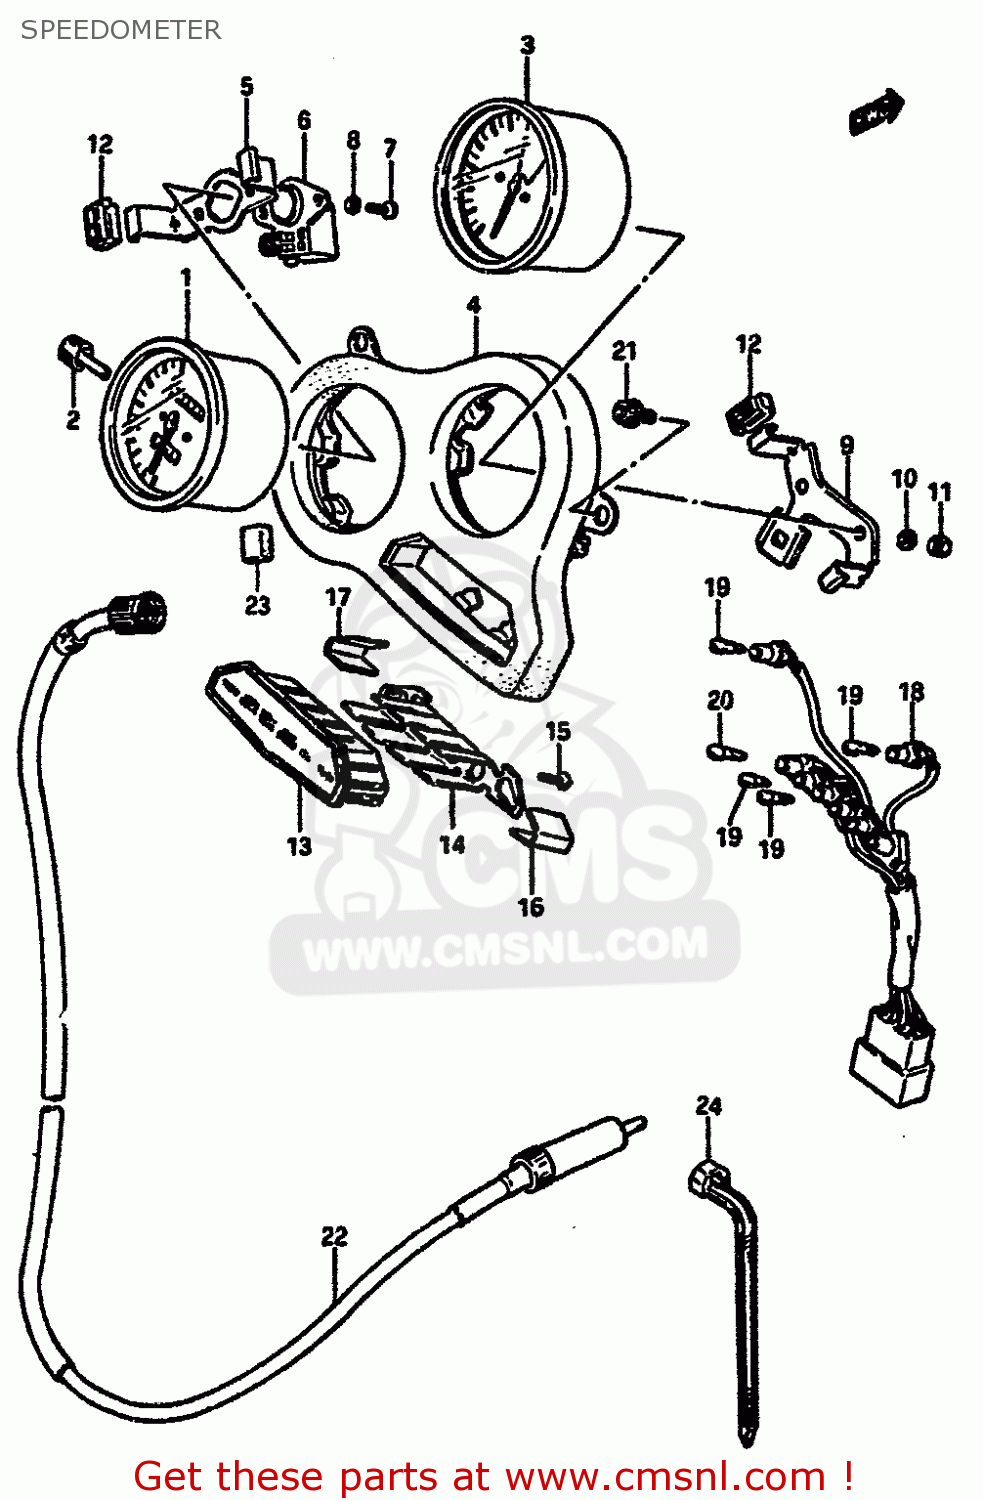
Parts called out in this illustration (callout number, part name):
1	SPEEDOMETER (KILO)
2	KNOB,TRIP
3	TACHOMETER
4	BRACKET, METER
5	PLATE,SPEEDOMETER
6	BOX,METER GEAR
7	SCREW
8	LOCK WASHER
9	PLATE,TACHOMETER
10	WASHER
11	NUT
12	CUSHION
13	CASE, PILOT LAMP
14	PLATE,PILOT LAMP
15	SCREW
16	PLATE,TURN,R
17	PLATE,TURN,L
18	SOCKET
19	BULB(12V3W,WB371,T7)
20	BULB(12V1.7W,WB372,T7)
21	BOLT
22	CABLE ASSEMBLY,SPEEDOMETER
23	CUSHION,METER
24	CLAMP(L:95)
